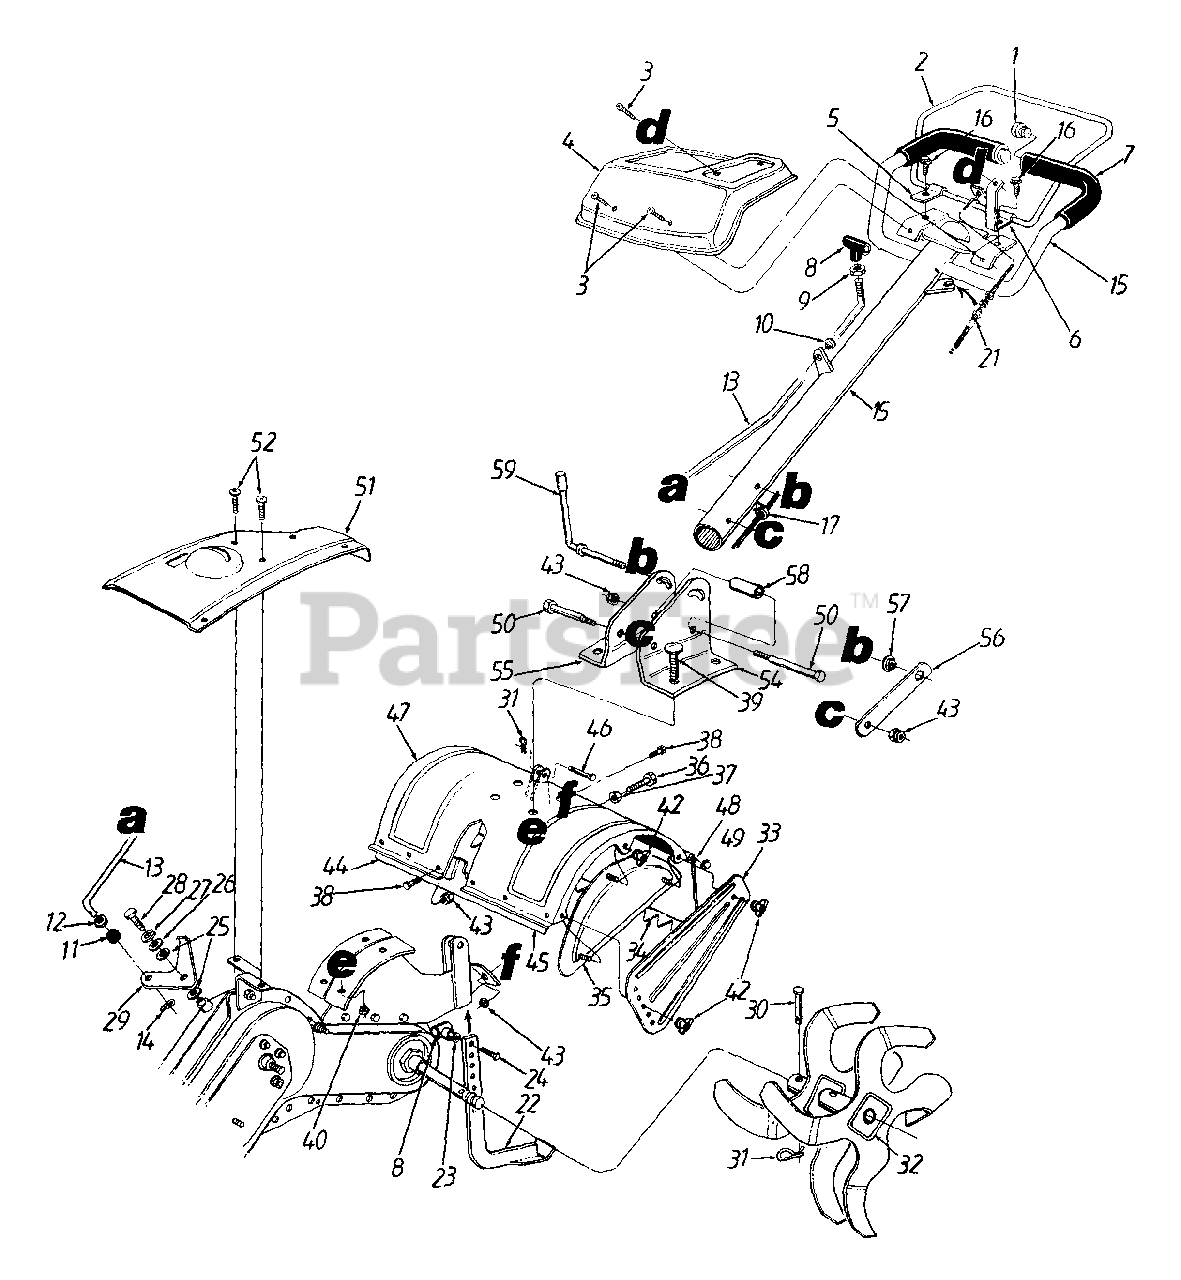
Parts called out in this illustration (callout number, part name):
1	Vinyl End Plug
3	Torx Mach. AB-Tap Scr. 1/4 x .62" Lg.
7	Grip
9	Hex Jam Nut 3/8-16 Thd.
10	Bushing 3/8" I.D.
11	Rubber Washer
12	Fl-Wash. .344" I.D. x .6" O.D.
13	Gear Shift Rod
14	Hairpin Clip
21	Clutch Cable
23	Fl-Wash. 3/8" I.D. x 5/8" O.D.
24	Hex Bolt 3/8-16 x .75" Lg.
25	Washer 1" O.D. (Hdn.)
26	Fl-Wash. .281" I.D. x .73" O.D.
27	L-Wash. 1/4" I.D.
28	Hex Bolt 1/4-20 x .62" Lg. (Gr. 5)
36	Hex Cap Bolt 5/16-18 x 1.25" Lg.
37	Hex Nut 5/16-18 Thd.
38	Hex Bolt 5/16-18 x .75" Lg.
39	Carriage Bolt 3/8-16 x 1" Lg.
40	Hex Ins. L-Nut 3/8-16 Thd.
42	Wing Nut 5/16-18 Thd.
43	Hex Flange Top L-Nut 5/16-18 Thd.
46	Clevis Pin .375" Dia.
49	Cap Speed Nut
50	Hex Bolt 5/16-18 x 3" Lg.
52	Torx Mach. AB-Tap Scr. 1/4 x .6"
57	Hex Flange Nut 3/8-24 Thd.
58	Spacer .322 Dia.
59	Handle Adjustment Crank
